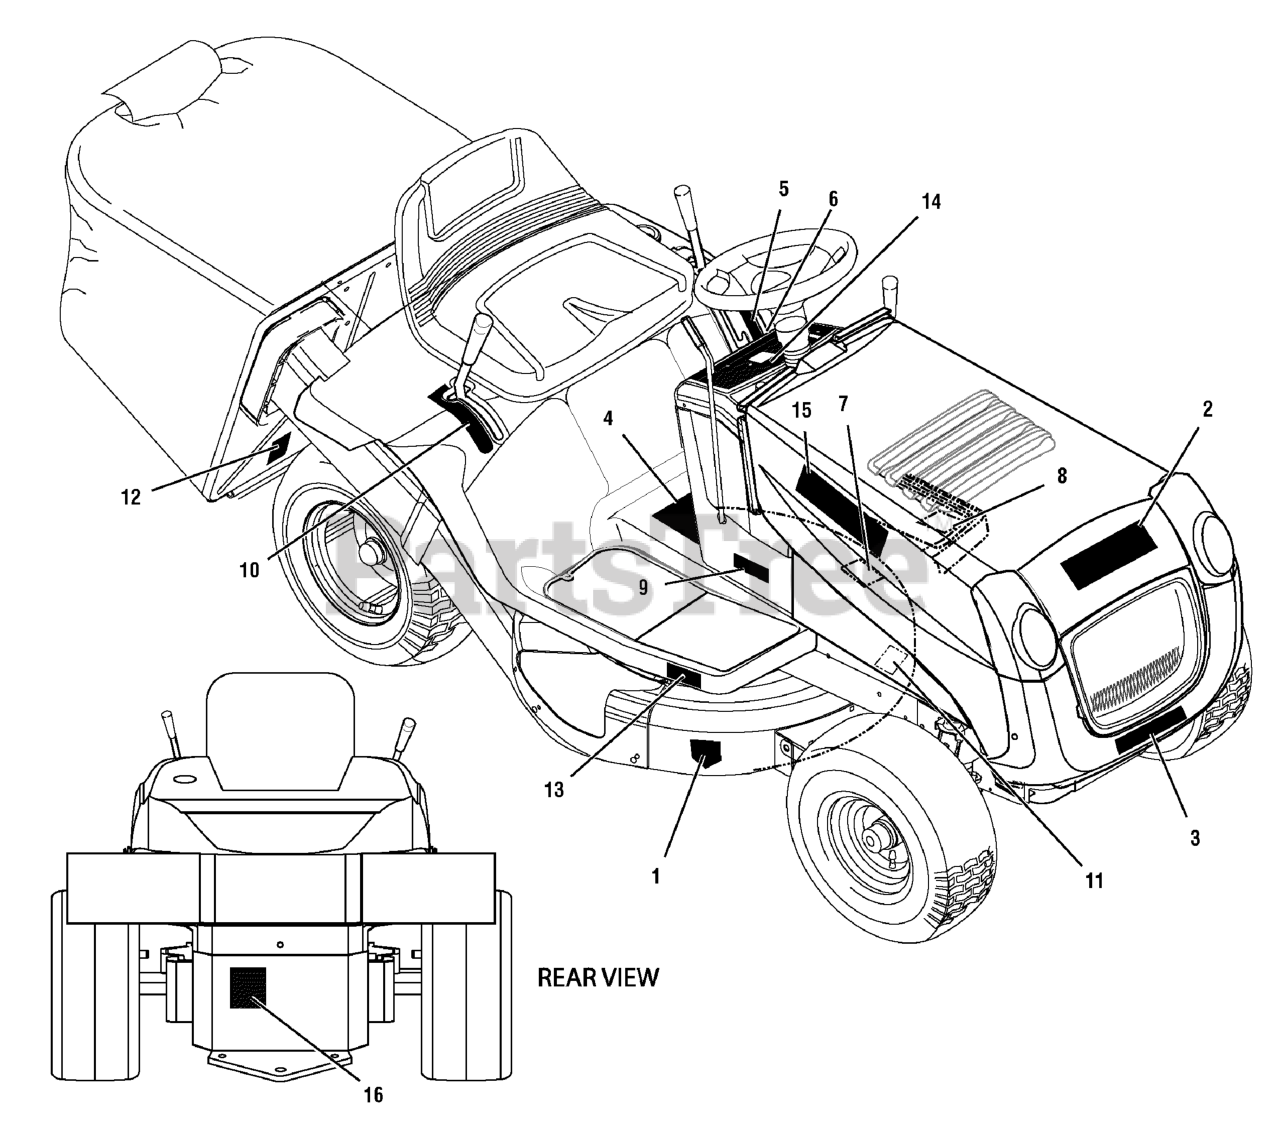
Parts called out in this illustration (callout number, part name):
1	DECAL, Cut Fingers Signal
2	DECAL, Hayter Emblem
3	DECAL, 13/30
4	DECAL, Warning Export
5	DECAL, 7 Position Cut Height
6	DECAL, Deck Level
7	DECAL, No Step Export
8	DECAL, Brake/Clutch Export
9	DECAL, B&S Logo
10	DECAL, 5 Speed
11	DECAL, Heat Shield Warning
12	DECAL, Warning Load Limit Export
13	DECAL, Warning Pinch Point
14	DECAL, Dash Symbols W1
15	DECAL, Hayter Heritage
16	DECAL, 100db Export/Serial Tag Identification
